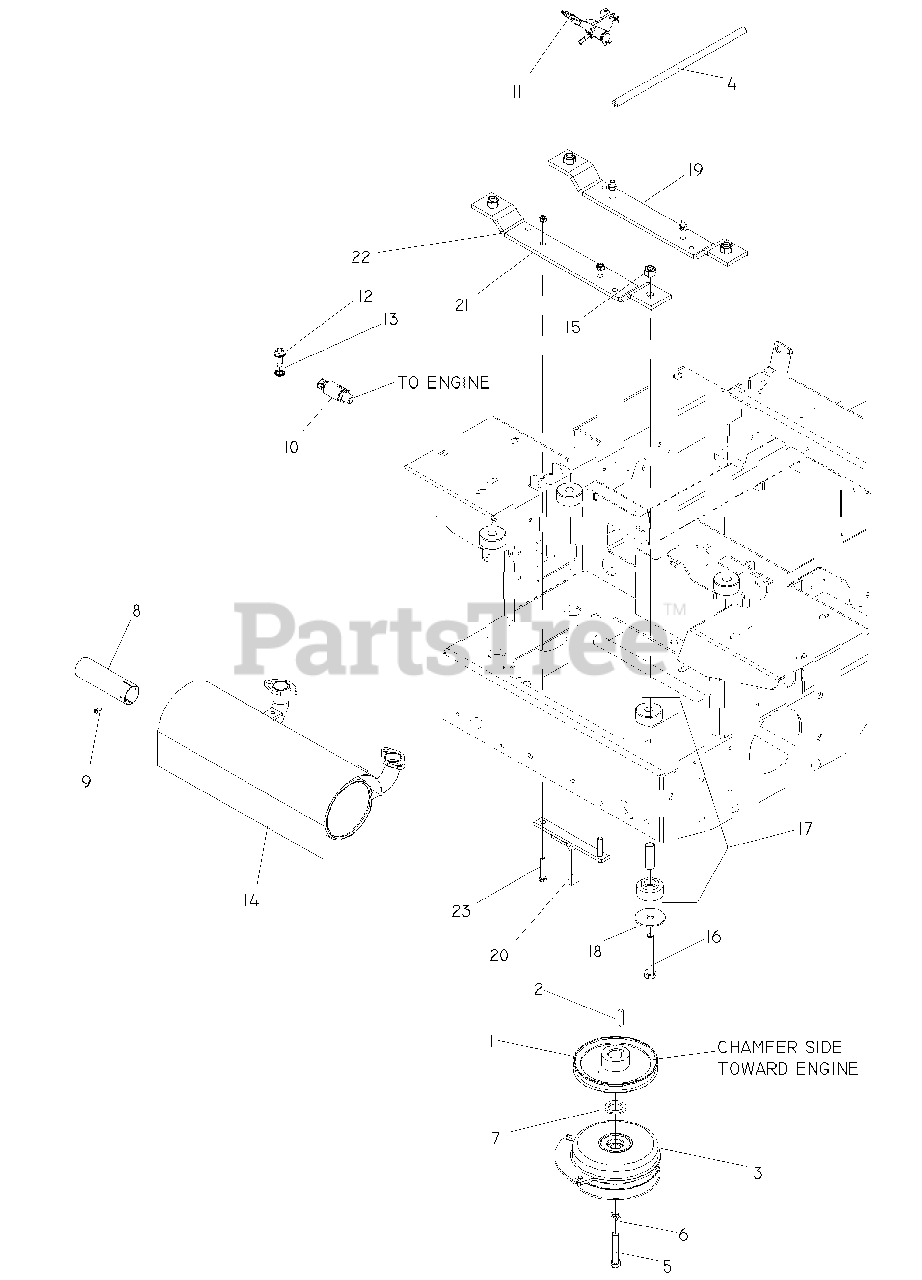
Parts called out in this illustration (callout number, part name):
2	KEY, 1/4 SQ X 1 1/4
3	CLUTCH-200 FT LB(RPLS 5218-102
4	FUEL LINE 13"
5	BOLT 7/16F X 2 1/2
6	WASHER 7/16 LOCK
7	BUSHING, 10GA MACHINERY
8	TUBE, EXTENSION, MUFFLER
9	SCR #8 X 1/2 PHIL HD DRILL BLK
10	OIL DRAIN FITTING
11	CHOKE CABLE
12	BOLT 3/8-16 X 1.0
13	WASHER 3/8 EXT STAR ZD
14	MUFFLER
15	NUT 1/2-13 HEX NYLOC ZD
16	HCS 1/2C X 3 1/4
17	ISOLATORS
18	ISOLATOR WASHER
19	ENGINE MOUNT
20	CLUTCH TIE DOWN
21	STRAP, ISO, REAR
22	NUT 5/16C CENTERLOCK
23	HCS 5/16-18 X 1-3/4 SERATED
